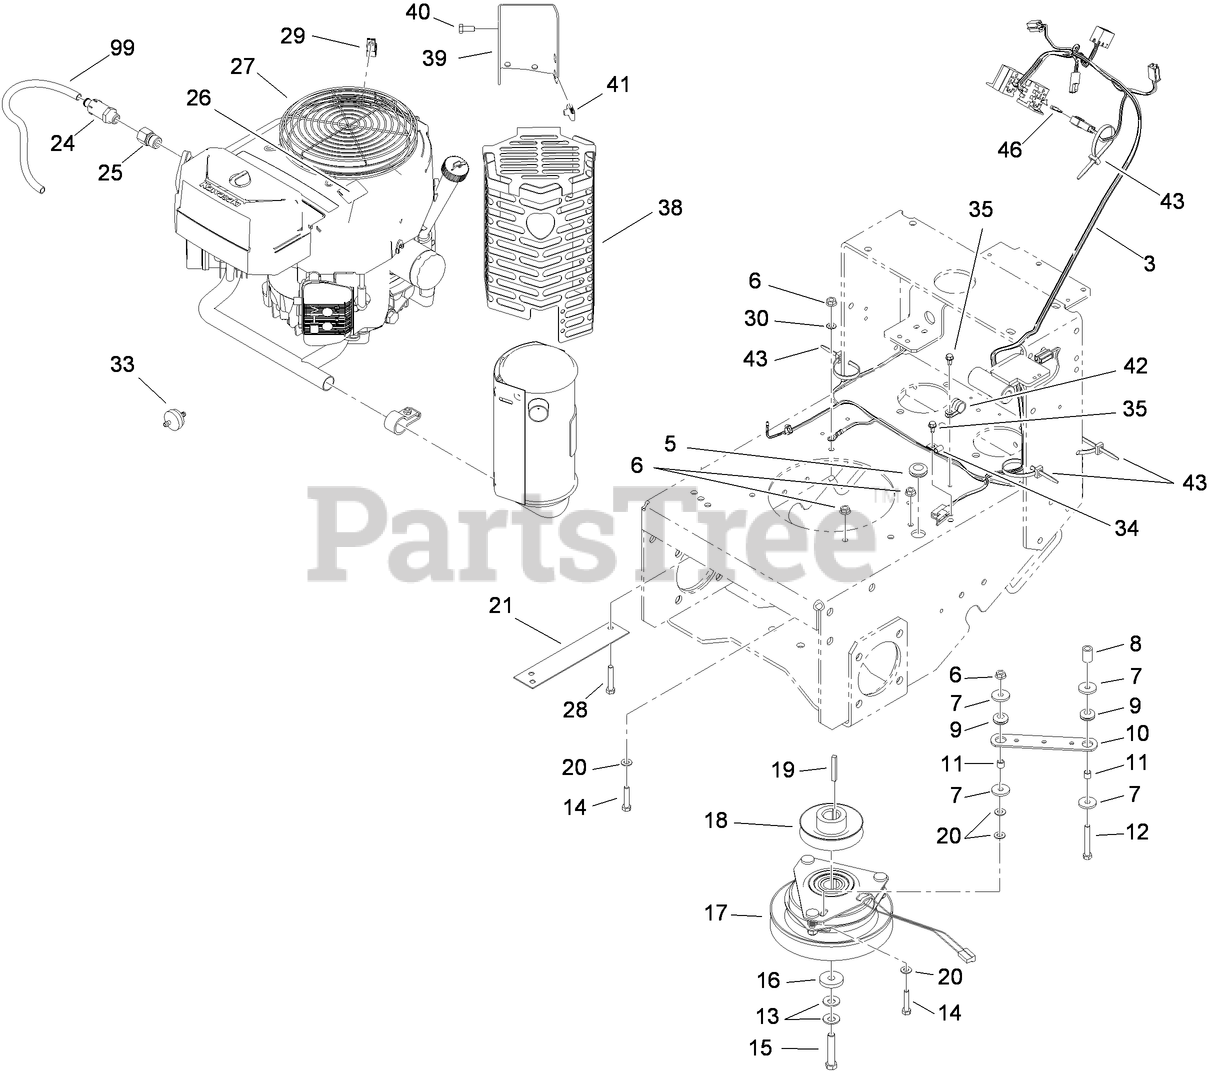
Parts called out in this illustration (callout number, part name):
3	HARNESS-WIRE
5	GROMMET
6	NUT-HF
7	WASHER
8	TUBE-RETAINER
9	GROMMET
10	STRAP-CLUTCH, BRAKE
11	SPACER
12	SCREW-HH
13	WASHER-SPRING
14	SCREW-HH
15	SCREW-HH
16	WASHER
17	CLUTCH / BRAKE ASM
18	Pulley
19	KEY-SQUARE
20	WASHER-PLAIN
21	COVER-PULLEY
24	VALVE-DRAIN, OIL
25	Adapter
26	DECAL-WARNING
28	SCREW-HH
29	CLAMP-CABLE
30	WASHER-LOCK
33	FILTER-FUEL
34	CLIP-CLOSED, INSULATED
35	SCREW
38	MUFFLER SHIELD ASM
39	BRACKET-MUFFLER
40	SCREW-HH
41	NUT-U
42	CLAMP-R
43	TIE-CABLE
46	FUSE-BLADE, 10 AMP
99	HOSE-DRAIN, OIL
